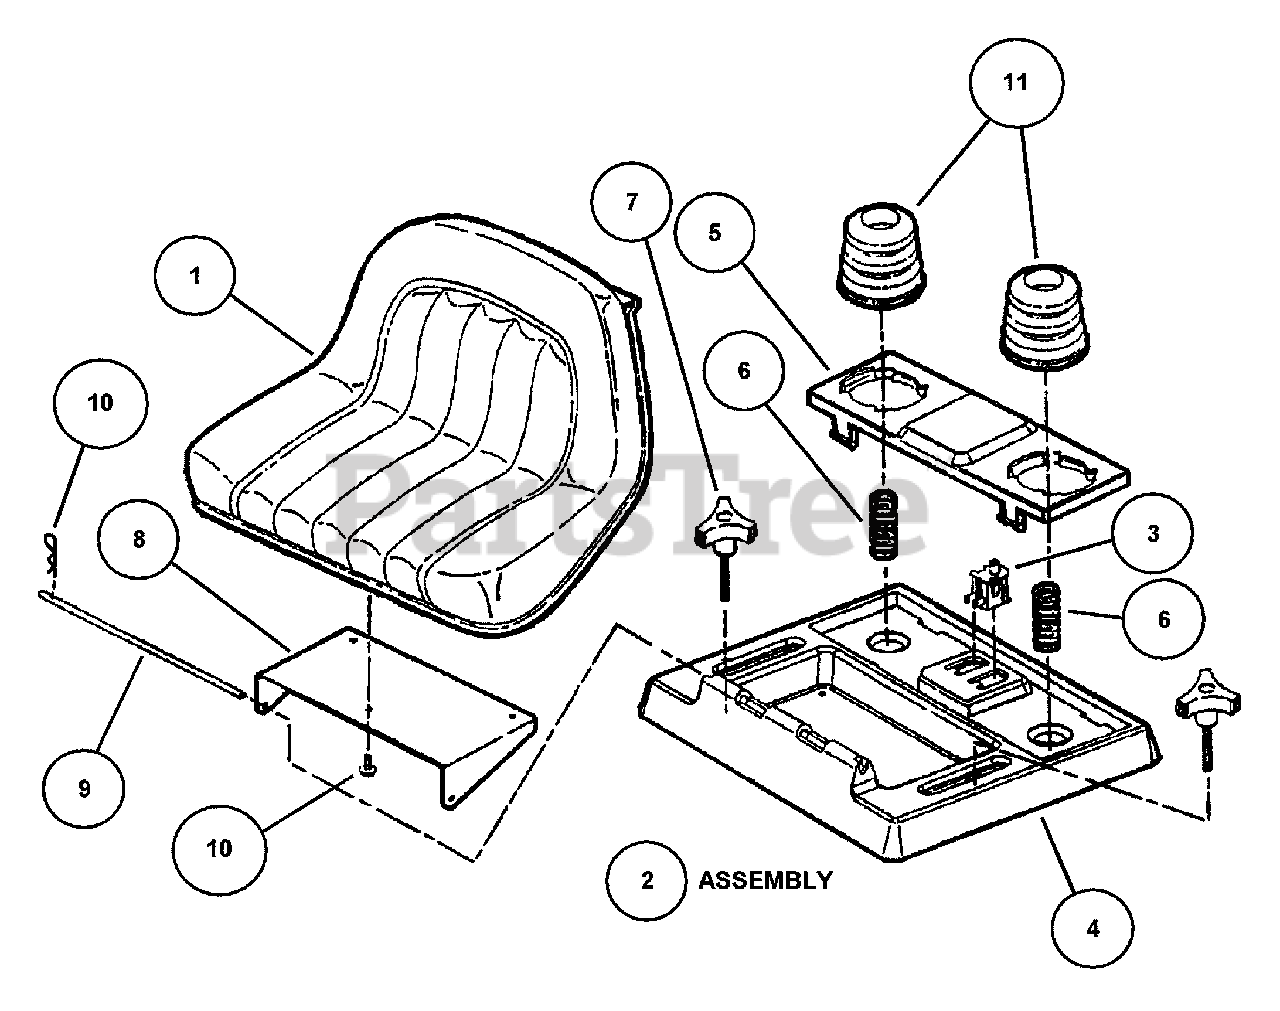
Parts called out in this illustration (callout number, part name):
1	SEAT, MILSCO HIGH BACK
2	ASSEMBLY, SEAT SUPPORT
3	SWITCH, SEAT, NC (DRIVER SIDE ONLY)
4	SUPPORT, SEAT
5	HOLDER, SEAT CUSHION
6	SPRING, CUSHION HOLDER
7	KNOB, 3 PRONG 5/16-18 X 2" STUD
8	SUPPORT, SEAT, UPPER
9	ROD, SEAT HINGE
10	PIN, HAIR, 3/13 X 1.5 YZ
11	CUSHION, SEAT
12	HFLB,5/16-18 X 1/2 GR5
